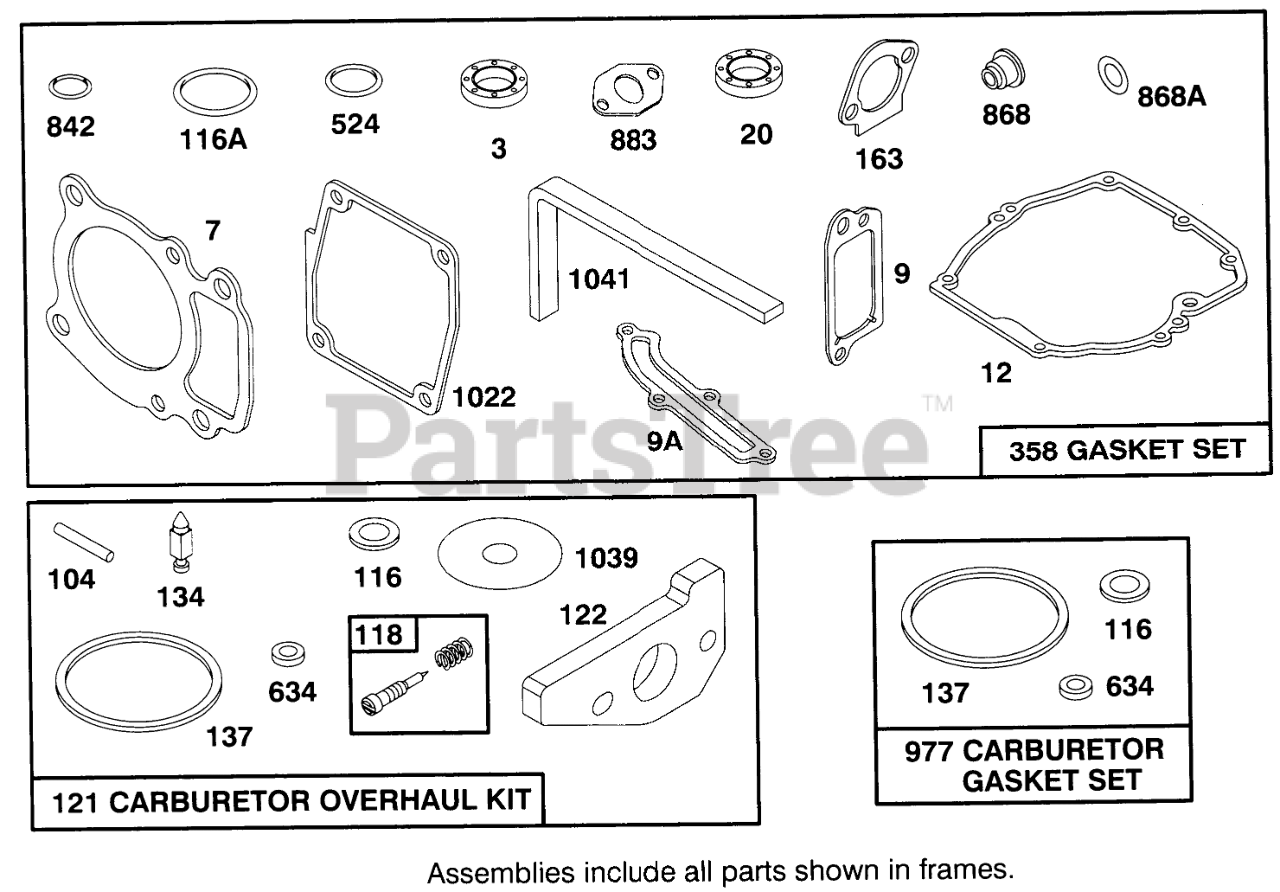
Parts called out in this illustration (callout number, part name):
3	SEAL - OIL
7	CYLINDER HEAD GASKET
9	BREATHER GASKET
9A	GASKET-BREATHER
12	ENGINE BASE GASKET
20	SEAL-OIL
104	FLOAT HINGE PIN
116	SEALING GASKET
116A	O RING SEAL
118	VALVE KIT - NEEDLE
121	CARBURATOR OVERHAUL KIT
122	ADAPTER ASSEMBLY
134	Valve-Inlet(Includes Seat)
137	FLOAT BOWL GASKET
163	AIR CLEANER GASKET
358	GASKET SET
524	O-RING
634	SEAL WASHER
842	O-RING
868	SealAssy-Valve
868A	Seal-Valve
883	EXHAUST GASKET
977	CARBURATOR GASKET SET
1022	ROCKER COVER GASKET
1039	VENT TUBE
1041	SEAL - FOAM
